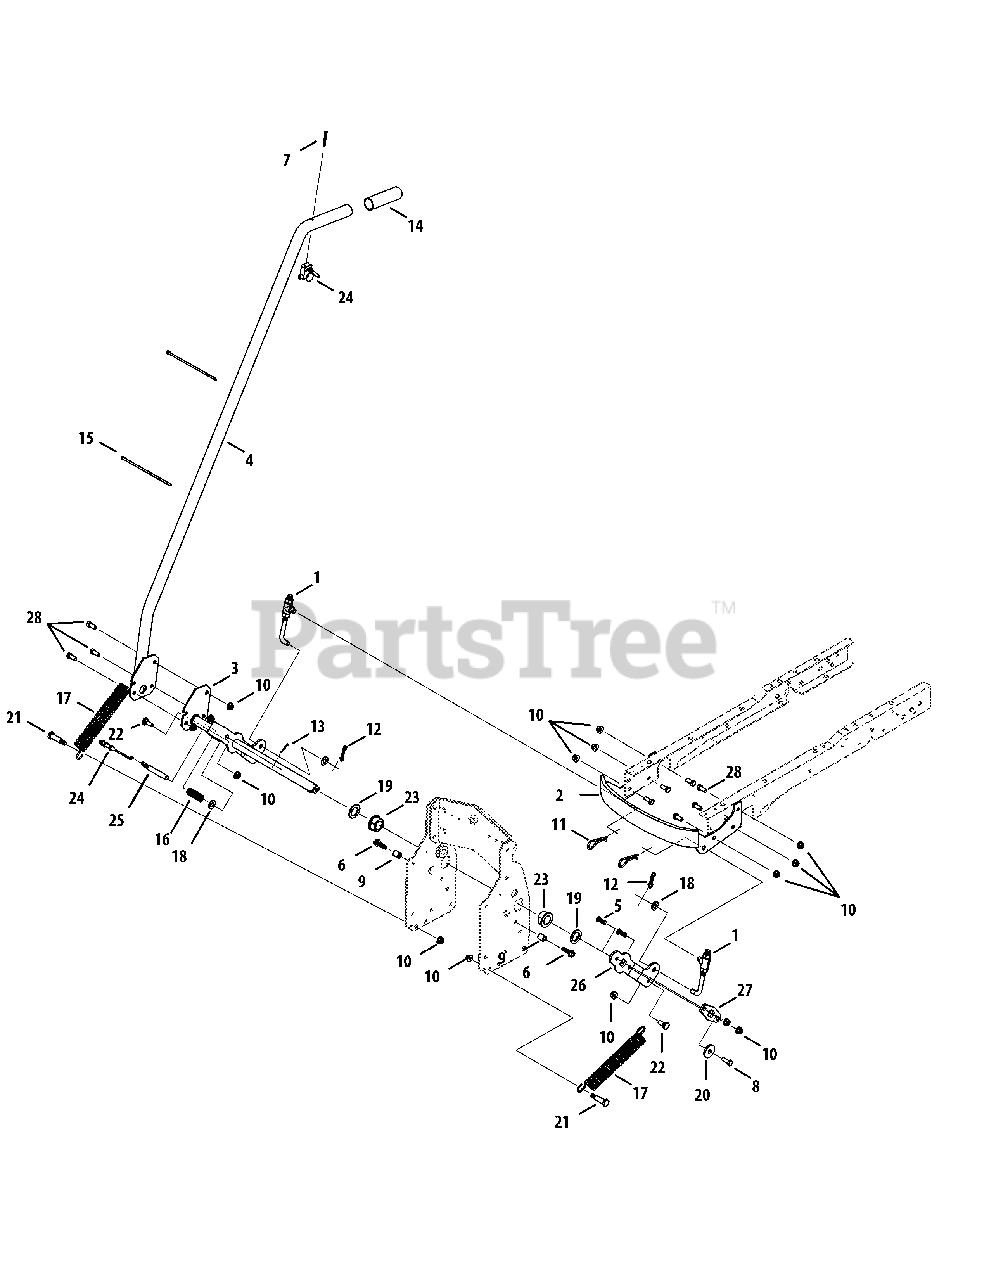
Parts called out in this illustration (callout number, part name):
1	Ferrule, .510 x .496
1	Hex Nut, 1/2-13
2	Bumper Assembly
3	Shft Assembly, Lift
4	Handle Assembly, Lift
5	Hex Screw, 3/8-16, 1.00, Gr5
6	Screw, Self-tapping, 3/8-16, 1.25
7	Screw, Oval, #10-24 x 1.75
8	Hex Screw, 3/8-16, 1.00, Gr5, Lock
9	Spacer, .385 x .623 x .750 Lg
10	Nut, Flange Lock, 3/8-16, Grf, Nylon
11	Pin, Cotter, Int, .148 x 3.00
12	Pin, Bow, 7/16"-1/2"
13	Pin, Cotter, 3/32 x 1.25
14	Grip, 1.188 ID x 4.562 Lg.
15	Cable, Tie, 3/16 x .05 x 7.4
16	Spring, Comp, .772 OD x 1.95 Lg
17	Spring Extension, 1.45 OD x 6.00
18	Washer, Flat, .510 x 1.00 x .060
19	Washer, Flat, 1.031 X1.620 x.095
20	Washer, Flat, .45 x 1.5 x .172, Ht
21	Screw, Shoulder, .498 Dia. x 1.445
22	Bolt, Shoulder, .500 x .270, 3/8-16
23	Bearing, Flange w/ Flats
24	Cable, Snowblower Lift
25	Rod, Lock, Lift w/ Trigger
26	Bracket, Lift
27	Adapter, Lift, Link
28	Hex Screw, 3/8-16, .880
